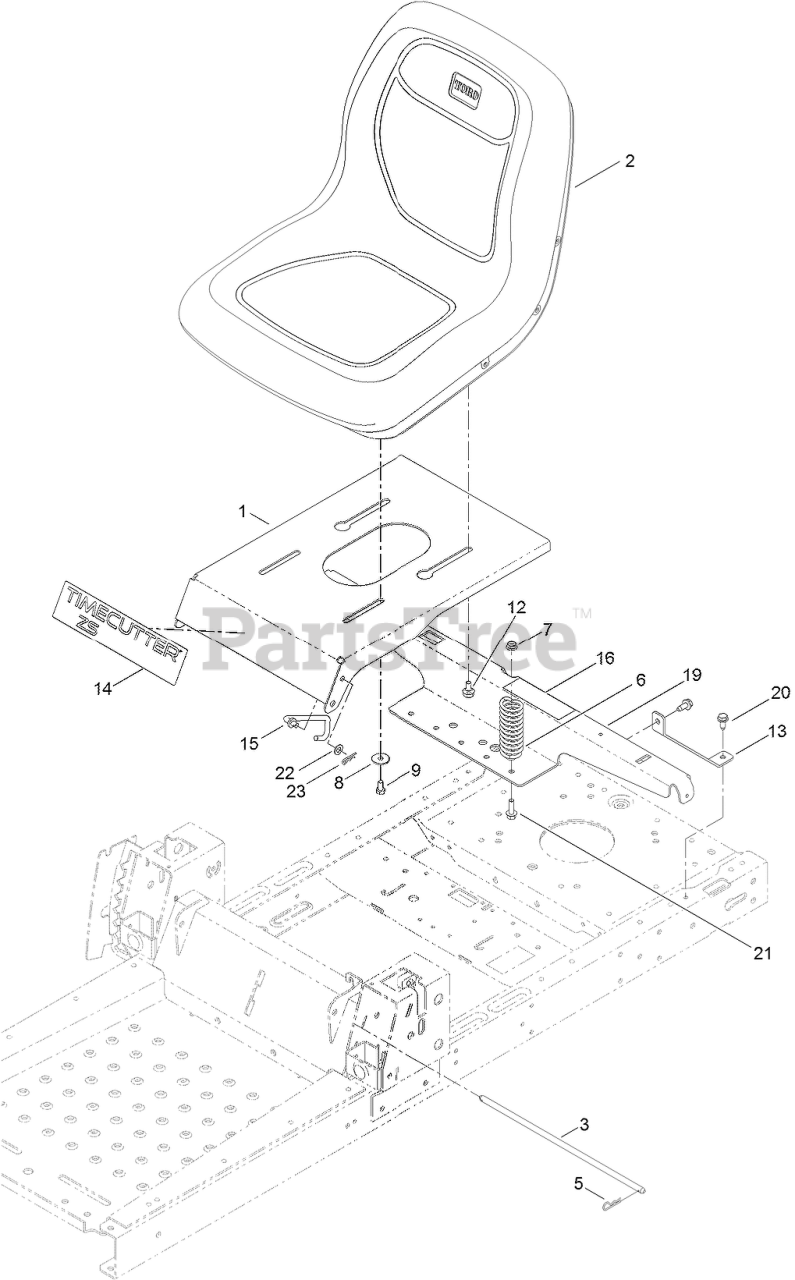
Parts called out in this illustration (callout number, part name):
1	PAN-SEAT
2	SEAT-18 INCH
3	ROD-PIVOT, NARROW
5	PIN-COTTER
6	SPRING-COMPRESSION
7	NUT-HF, NI
8	WASHER-PIVOT
9	SCREW-HH
12	BOLT-SHOULDER
13	SUPPORT-TANK, REAR
14	DECAL-TIMECUTTER
15	STOP-SEAT
16	DECAL-SERVICE, CE
19	SUPPORT-POD
20	SCREW-HWHTF
21	SCREW-HHF
22	WASHER-PLAIN
23	PIN-COTTER
